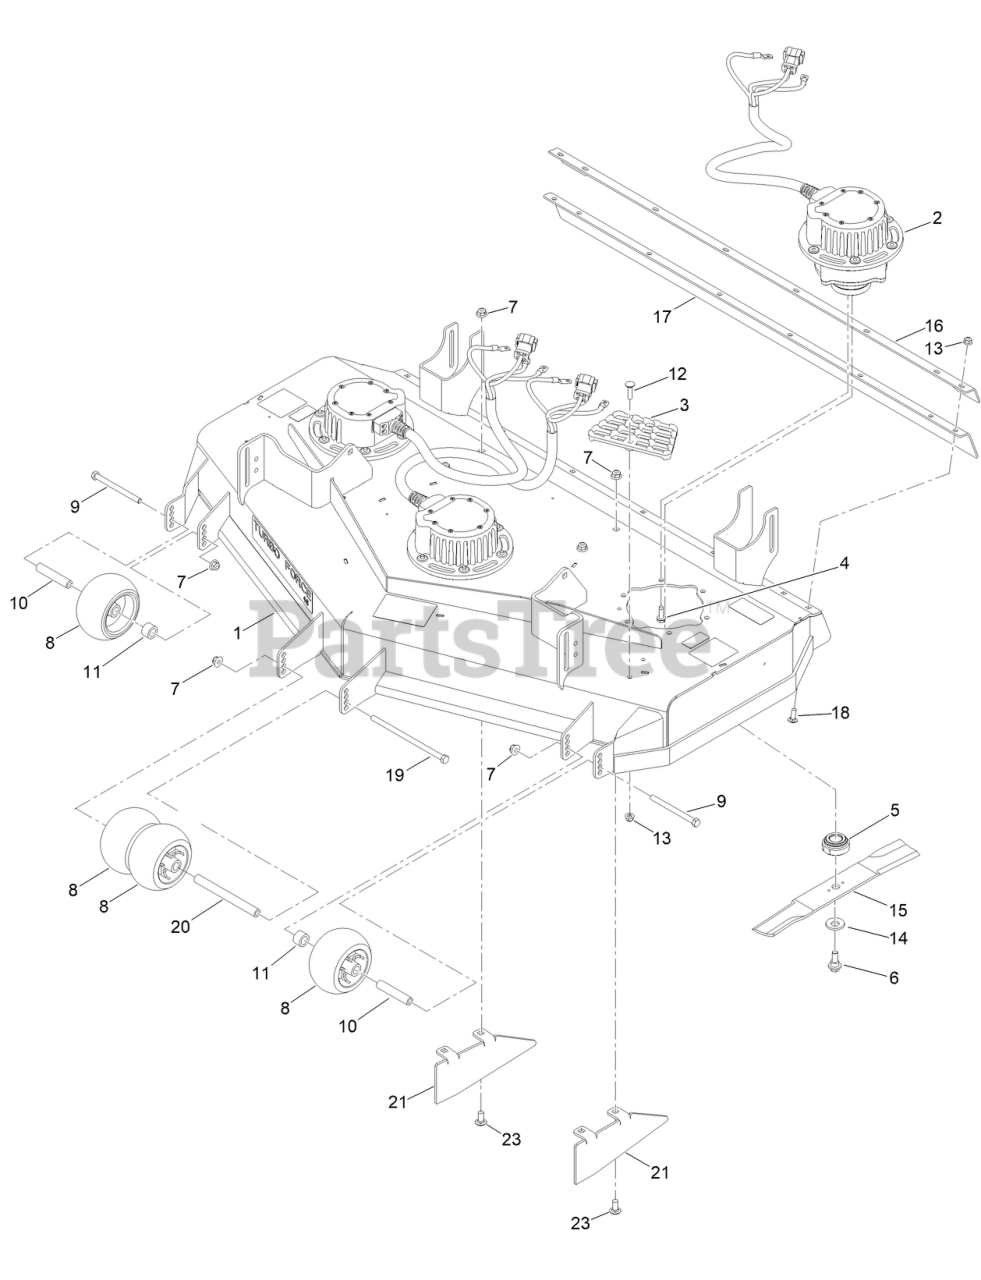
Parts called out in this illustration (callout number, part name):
1	DECK ASM-48IN, RD
2	MOTOR/GEN-48V,
3	STEP-DECK
4	SCREW-THD ROLL, HWH
5	RETAINER-BLADE
6	SCREW-SHOULDER,HWH
7	NUT-HF, NI
8	ROLLER-SCALP, ANTI
9	SCREW-HH
10	TUBE-SHAFTING
11	TUBE-SPACER
12	SCREW-CARR
13	NUT-HF, NI
14	WASHER-BELLEVILLE
15	BLADE-16.5IN, MED SAIL
16	DEFLECTOR, BRACKET-48RD
17	GUARD-RUBBER
18	BOLT-CARR
19	SCREW-HH
20	SPACER-WHEEL
21	BAFFLE-LONG
23	SCREW-CARR
